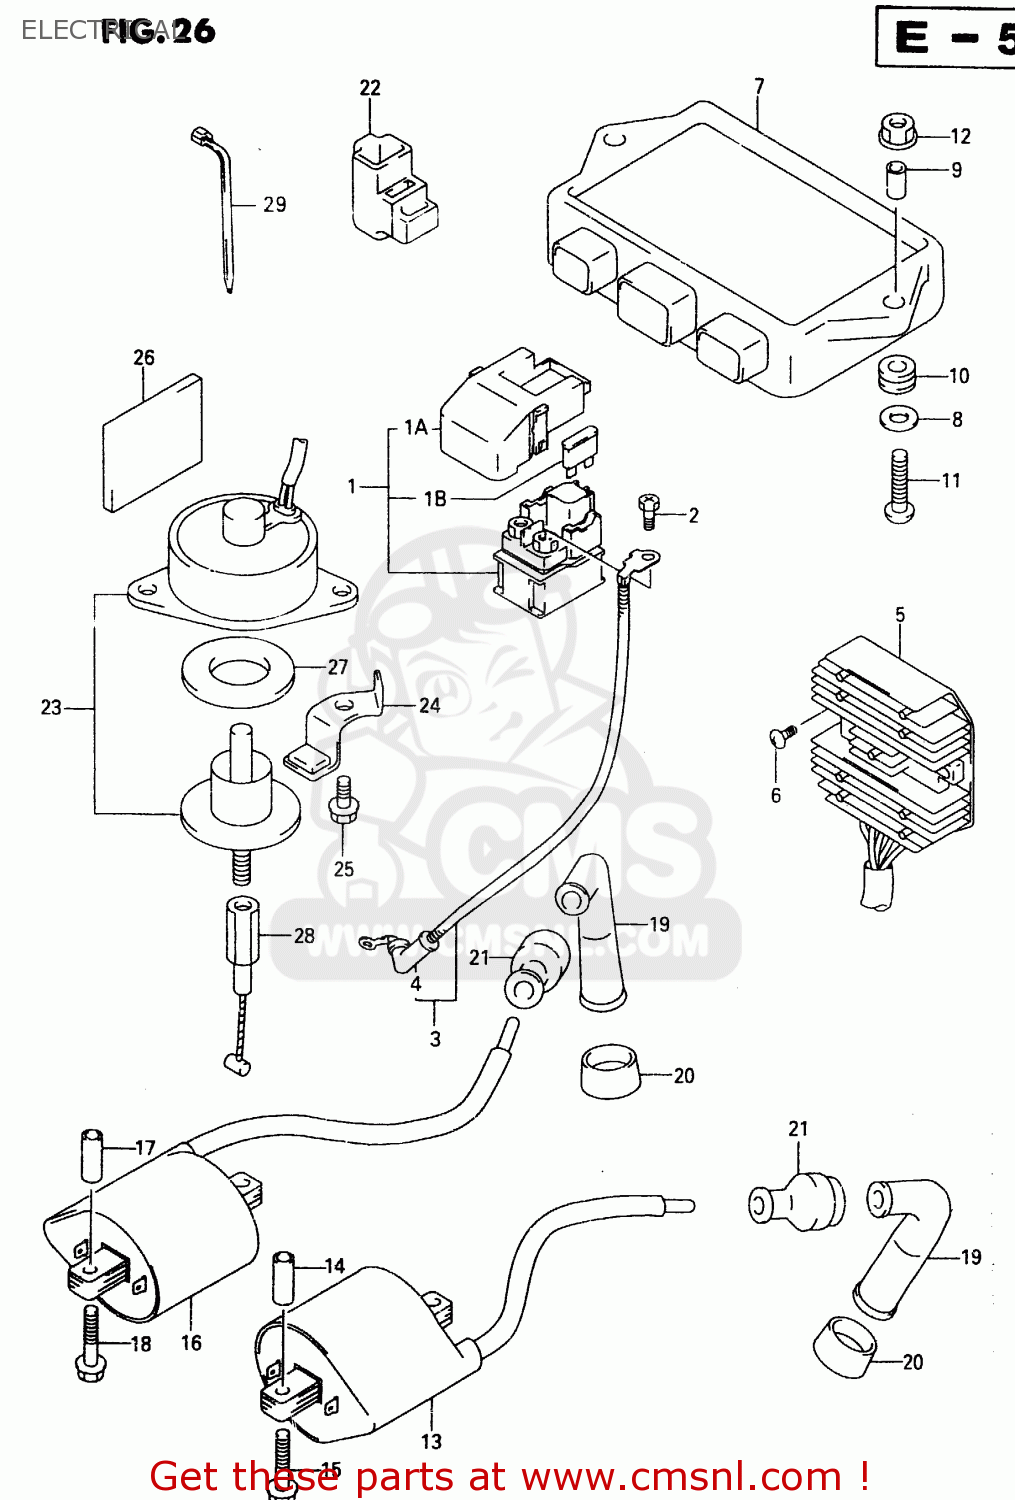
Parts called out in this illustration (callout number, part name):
1	RELAY ASSY,STARTING MOTOR
1A	COVER,RELAY ASSEMBLY
1B	FUSE(30A)
2	SCREW(6X8)
3	WIRE,STARTER MOTOR LEAD
4	CAP,STARTER MOTOR LEAD
5	RECTIFIER ASSEMBLY
6	SCREW
7	IGNITOR ASSY
8	WASHER(6.5X20X1.6)
9	SPACER(6.1X8X9.5)
10	CUSHION
11	SCREW
12	NUT
13	COIL ASSY,IGNITION
14	SPACER(6.4X10X18)
15	BOLT
16	COIL ASSEMBLY,IGNITION,FRONT
17	SPACER(6.4X10X18)
18	BOLT
19	CAP,SPARK PLUG
20	SEAL,SPARK PLUG CAP
21	SEAL,HIGH TENSION CORD
22	RELAY ASSY
23	SOLENOID ASSY,DECOMP
24	STOPPER,DECOMP SOLENOID
25	BOLT
26	CUSHION,BATTERY(80X27X3)
27	CUSHION,DECOMP
28	CABLE ASSY,DECOMP FR
29	CLAMP(L:235)
